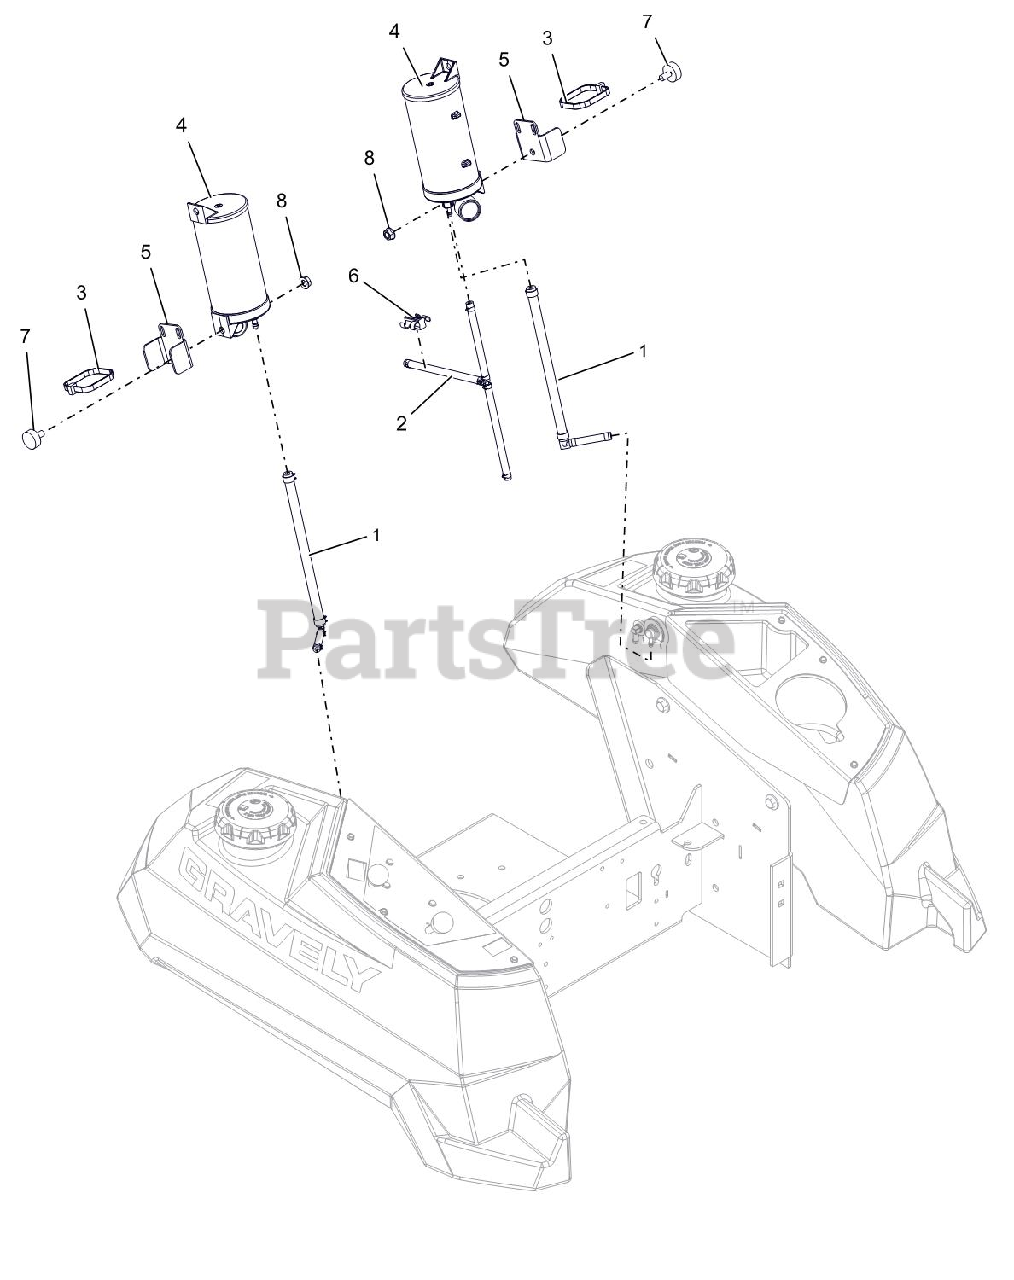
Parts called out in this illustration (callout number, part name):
1	ASM, CANISTER VENT LINE
2	ASM, VAPOR LINE (CARB)
3	TIE WRAP, 15.25" X 120 LBS
4	CANISTER, 400 CC CARB
5	CARB CANISTER MTG BRKT - BLACK
6	CLIP, T, .38-.50
7	BUMPER, RUBBER
8	@NUT-SPNLK-FLG .312-18 YWZC
